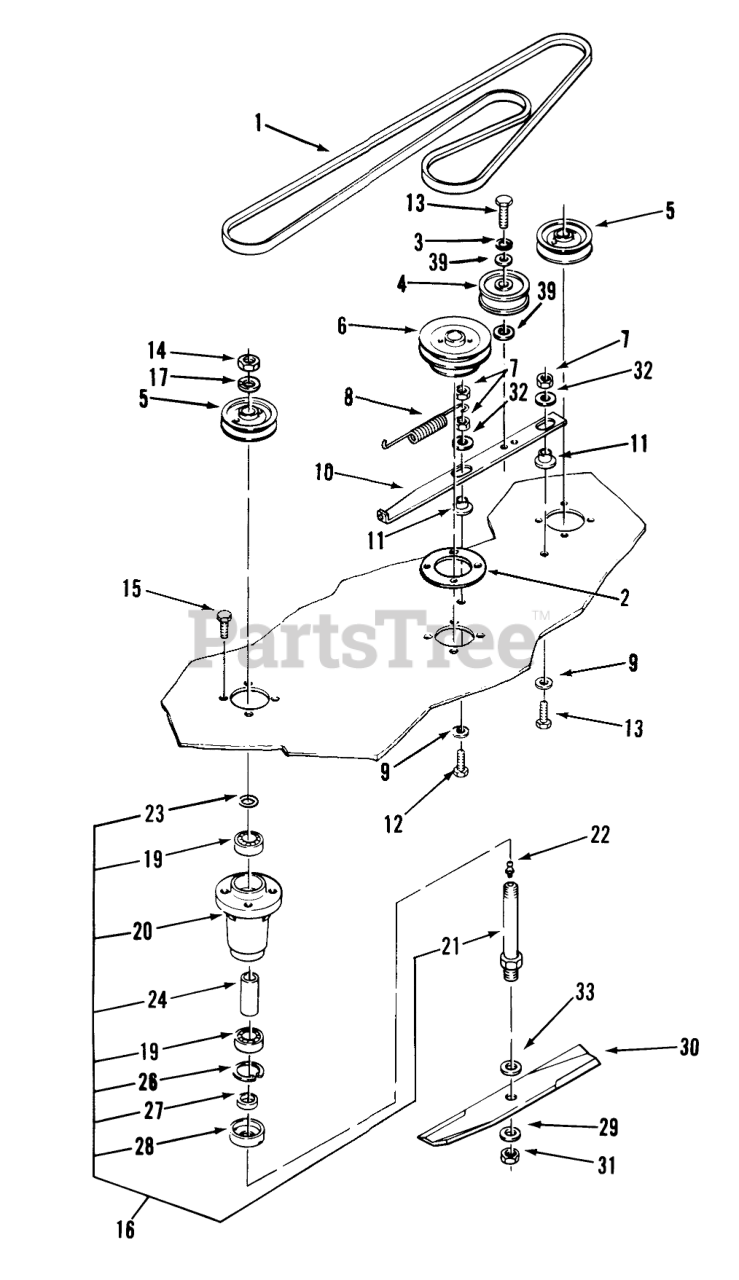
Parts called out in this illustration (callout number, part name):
1	V BELT
2	PLATE-SPINDLE
3	WASHER-LOCK
4	Idler Pulley
5	PULLEY
6	PULLEY
7	NUT-LOCK, NI
8	SPRING-EXTENSION
9	WASHER
10	BAR-IDLER SUPPORT
11	SPACER-BUSHING
12	SCREW-HH
13	SCREW-HH
14	NUT-JAM
15	SCREW-HH
16	Spindle Assembly
17	WASHER-LOCK
19	BEARING-BALL
20	HOUSING-SPINDLE
21	SHAFT-SPINDLE
22	FITTING-GREASE
23	O RING
26	RING-RETAINING
27	SPACER-BLADE
28	CUP-SPINDLE
29	WASHER-FLAT
30	BLADE-14IN
31	NUT-JAM
32	WASHER
33	Washer
